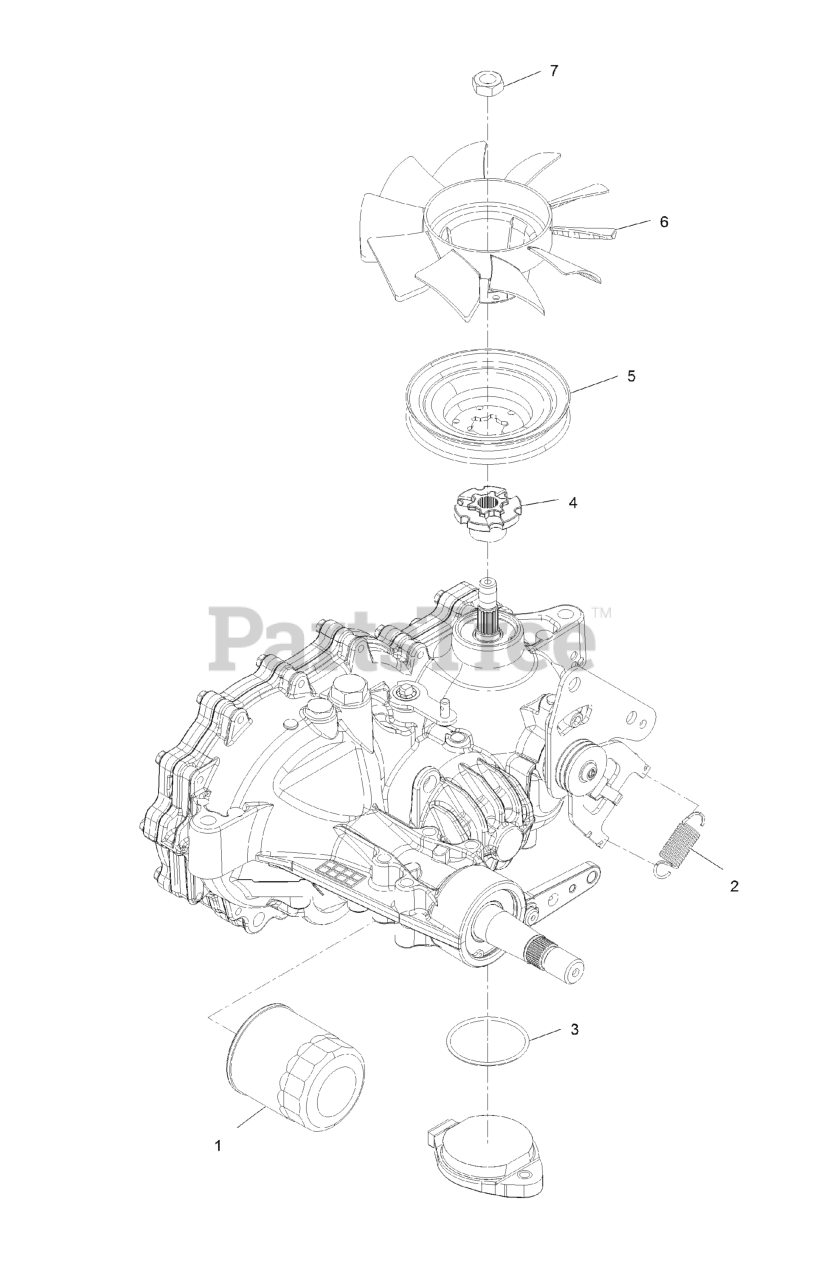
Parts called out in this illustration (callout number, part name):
1	ELEMENT-OIL FILTER, HYD
2	SPRING-EXTENSION
3	O RING-SEAL
4	HUB-PULLEY
6	FAN-7.0 INCH (10 BLADE)
